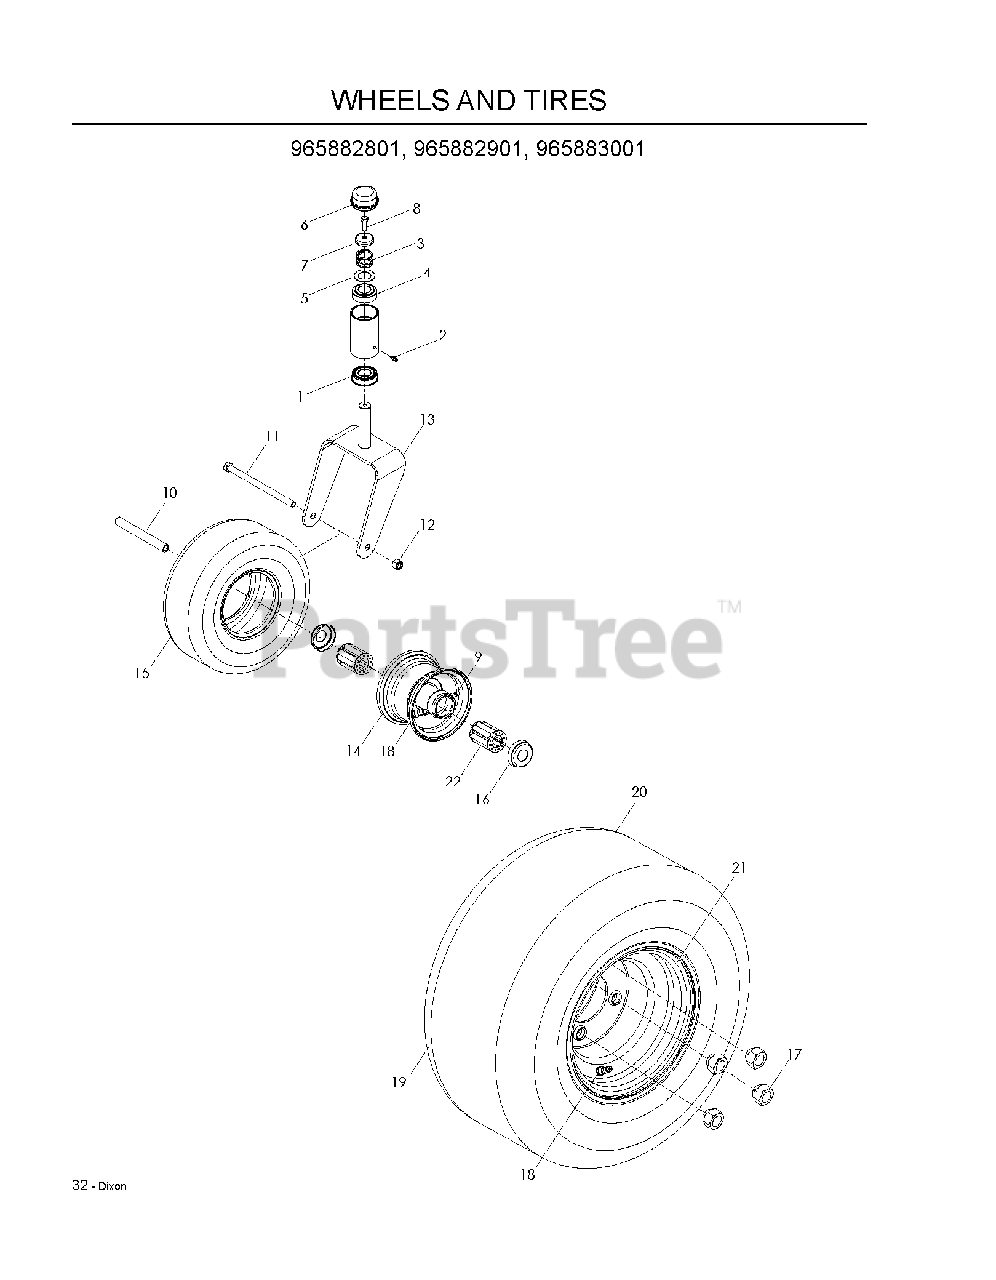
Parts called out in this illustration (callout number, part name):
1	BEARING FLANGED
2	ZERK, 3/16, DRIVE IN
3	SPRING, CASTER
4	BUSHING, CASTER
5	WASHER, 1.025 ID X 1.64
6	GREASE CAP
7	CASTER.PLUG
8	HCS 5/16C X 1
9	ZERK 1/8 NPT
10	SPACER, CASTER
11	SCREW 1/2C X 7 1/2 HEX CAP
12	NUT 1/2-13 HEX NYLOC ZD
13	YOKE, CASTER - BLUE
14	Tire Assembly, Complete
15	TIRE - FRONT
16	BEARING RETAINER
17	LUG NUT 1/2F
18	VALVE STEM TR-412
20	TIRE.22X9.5-10.TURF.TRAC.R/S
21	RIM 22 X 9.5-10
22	ROLLER BEARING
